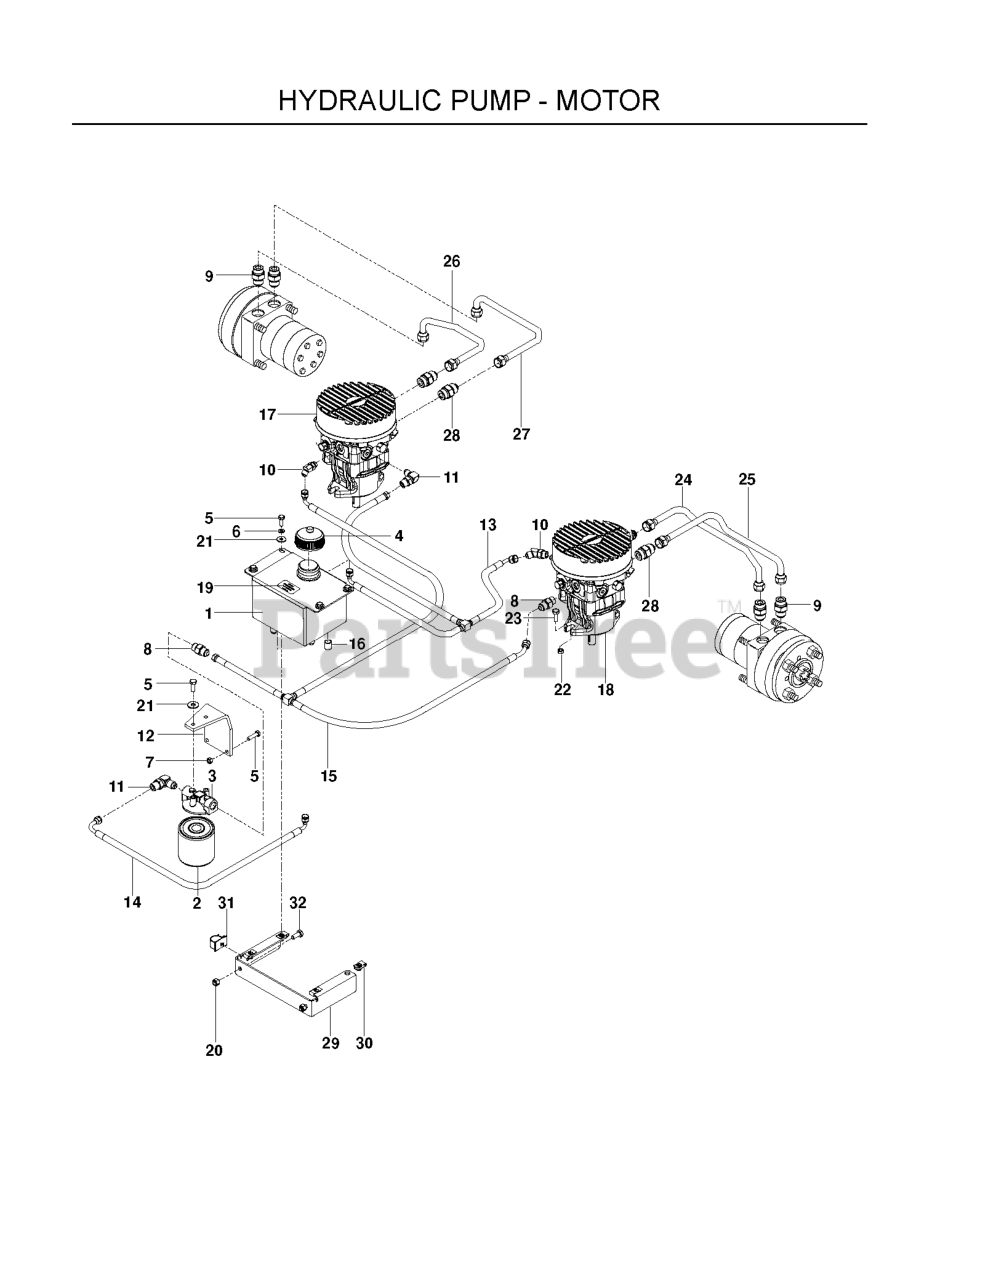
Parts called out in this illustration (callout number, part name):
2	HYDRAULIC OIL FILTER
3	FILTER HEAD
4	HYDRAULIC CAP
5	HCS 1/4C X 3/4 HCS
6	LOCKWASHER 1/4"
7	NUT.1/4-20.HEX.NYLOC.ZD
8	HYDRAULIC FITTING
10	45 DEG ADJ ELBOW
11	ELBOW, F6801-6-6-0 90 DEGREE
12	OIL FILTER BRKT
13	HOSE, T-ASM RETURN
14	HOSE, TANK - FILTER LINE
15	HOSE, T-ASM SUPPLY
16	NUT 9/16-18 JIC CAP
17	HG_PUMP, 10CC W/FAN RIGHT
18	HG_PUMP, 10CC W/FAN LEFT
19	DECAL, OIL TANK
20	NUT 5/16 NYLOC
21	WASHER 1/4 FLAT
22	NUT 3/8C CENTERBLOCK
23	4CS 3/8C X 1 SERRATED HEAD
24	HOSE, RPA - MA LINE
25	HOSE, RPB - MB LINE
26	HOSE, LPA - MB LINE
27	HOSE, LPB - MA LINE
28	FITTING, STRAIGHT F6400-8-8-0
29	TANK MOUNT
30	1/4C - U TYPE RETAINER
31	PUSH-MOUNT WIRE CLIP
32	HCS 5/16C X 3/4
